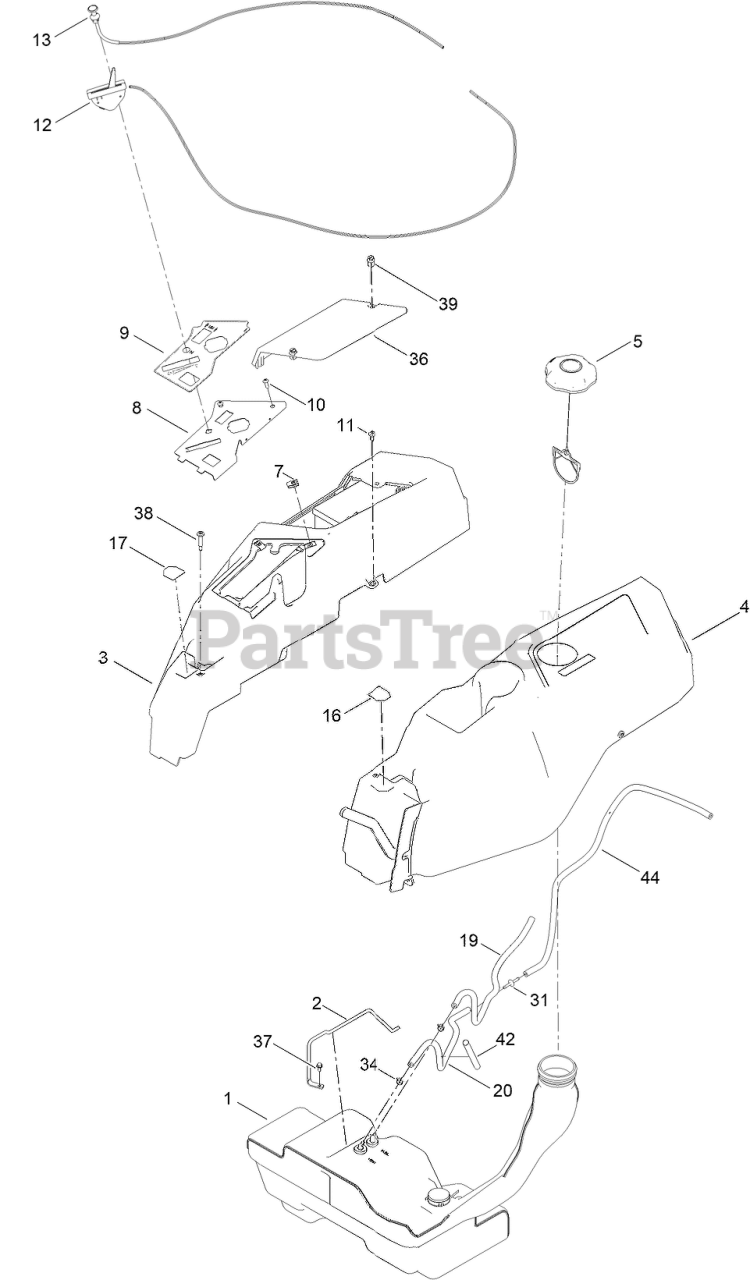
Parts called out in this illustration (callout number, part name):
1	TANK-FUEL ASM
2	ROD-HOLD DOWN
3	POD-RH
4	POD-LH
5	CAP-FUEL, RATCHETING
8	PANEL-CONTROL
9	DECAL-PANEL, CONTROL
10	SCREW-PRH
11	SCREW-SHOULDER
12	CABLE-THROTTLE
13	CABLE-CHOKE
16	DECAL-LEVER, CONTROL (LH)
17	DECAL-LEVER, CONTROL (RH)
19	HOSE-FUEL
20	HOSE-VENT
31	ADAPTER ORIFICE
34	CLAMP-HOSE
36	COVER-BATTERY
37	SCREW-HWH
38	SCREW-SHOULDER
39	FASTENER
42	SLEEVE-FUEL LINE PROTECTOR
44	HOSE-FUEL
